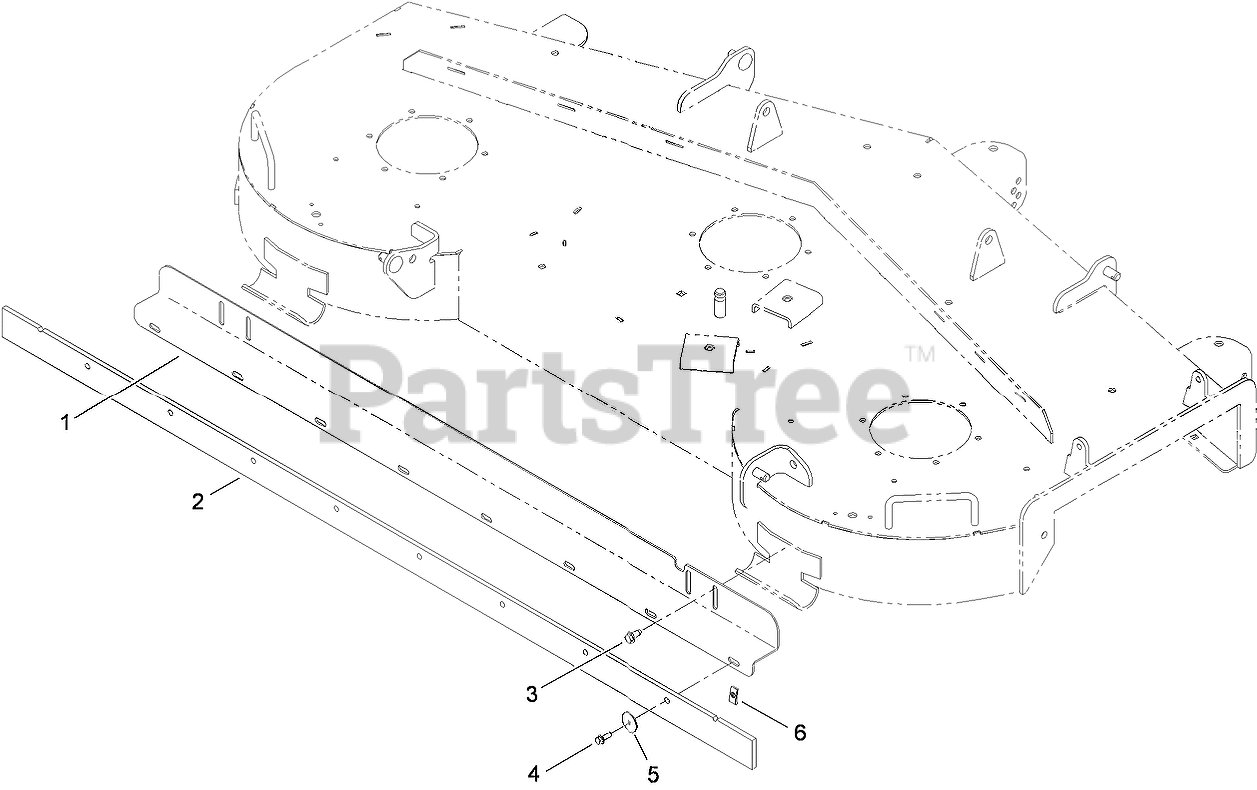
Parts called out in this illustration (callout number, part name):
3	SCREW-HWHTF
4	SCREW-HHF
5	WASHER-FLAT
6	NUT-SPEED
